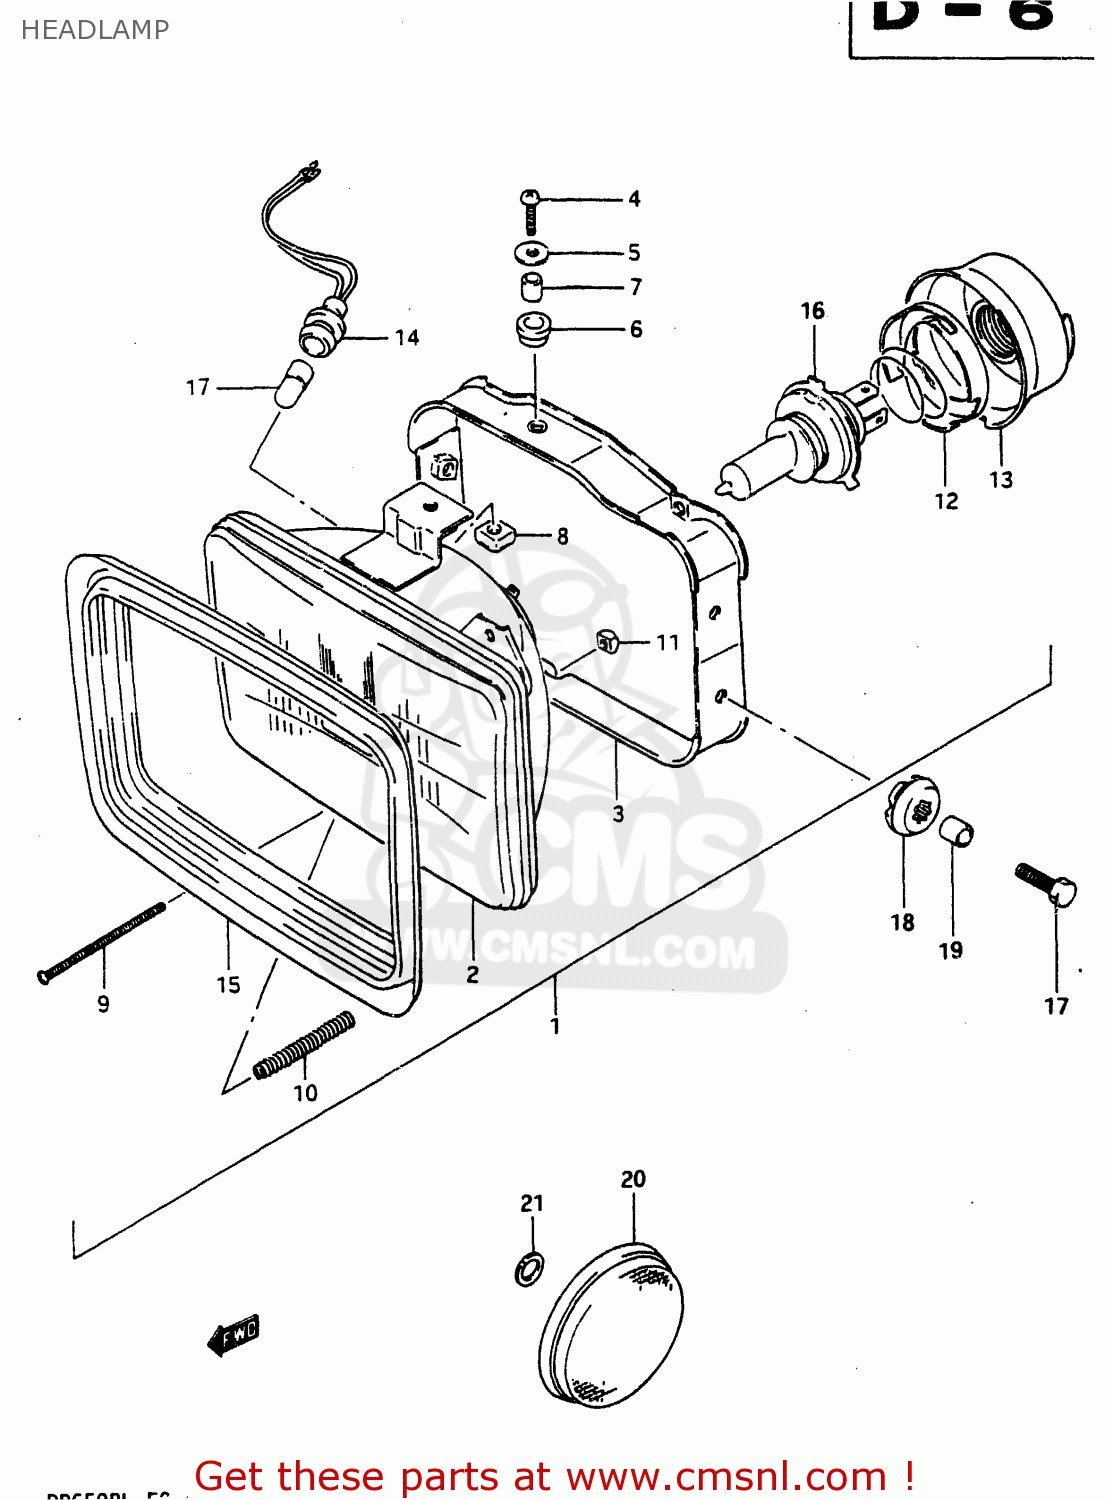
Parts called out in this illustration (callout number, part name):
1	HEADLAMP ASSY
2	UNIT
3	HOUSING
4	WASHER
5	CUSHION
6	SPACER
7	NUT
8	SCREW,HEADLAMP ADJUST
9	SPRING
10	NUT
11	HOLDER,BULB
12	COVER,SOCKET
13	SOCKET,PARKING
14	SHADE
15	BULB(12V60/55W,H4)
16	BULB(12V4W)
17	BOLT 6X20
18	CUSHION
19	SPACER (6.1X9X10)
20	REFLECTOR,REFLEX FR
21	LOCK WASHER
